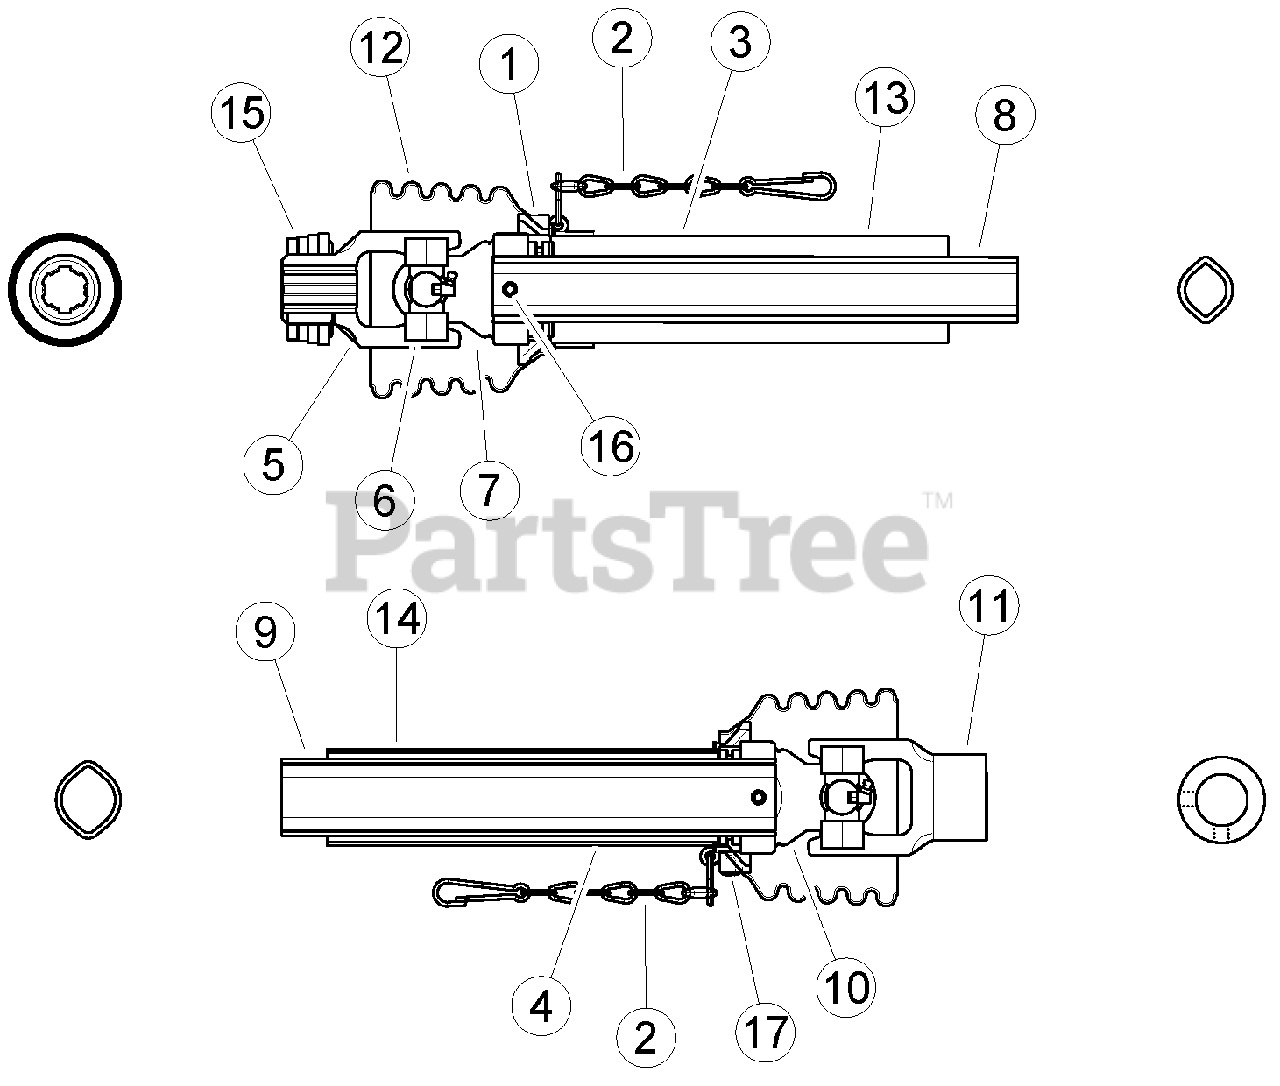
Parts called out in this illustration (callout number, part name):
1	BEARING, RING SC15
2	SAFETY CHAIN
3	DECAL, OUT
4	DECAL, IN
5	YOKE, 3/8 - 6 SPL. ASGE
6	CROSS & BEARING KIT
7	YOKE, INBOARD OV
8	INNER PROFILE OV
9	OUTER PROFILE I
10	YOKE, INBOARD I
12	SHIELD, CONE 4 RIB
13	SHIELD, OUTER TUBE OVL.
14	SHIELD, INNER TUBE RND
15	KIT, RETAINING RING / TRACTOR SIDE
16	PIN, SPRING 10 X 65
